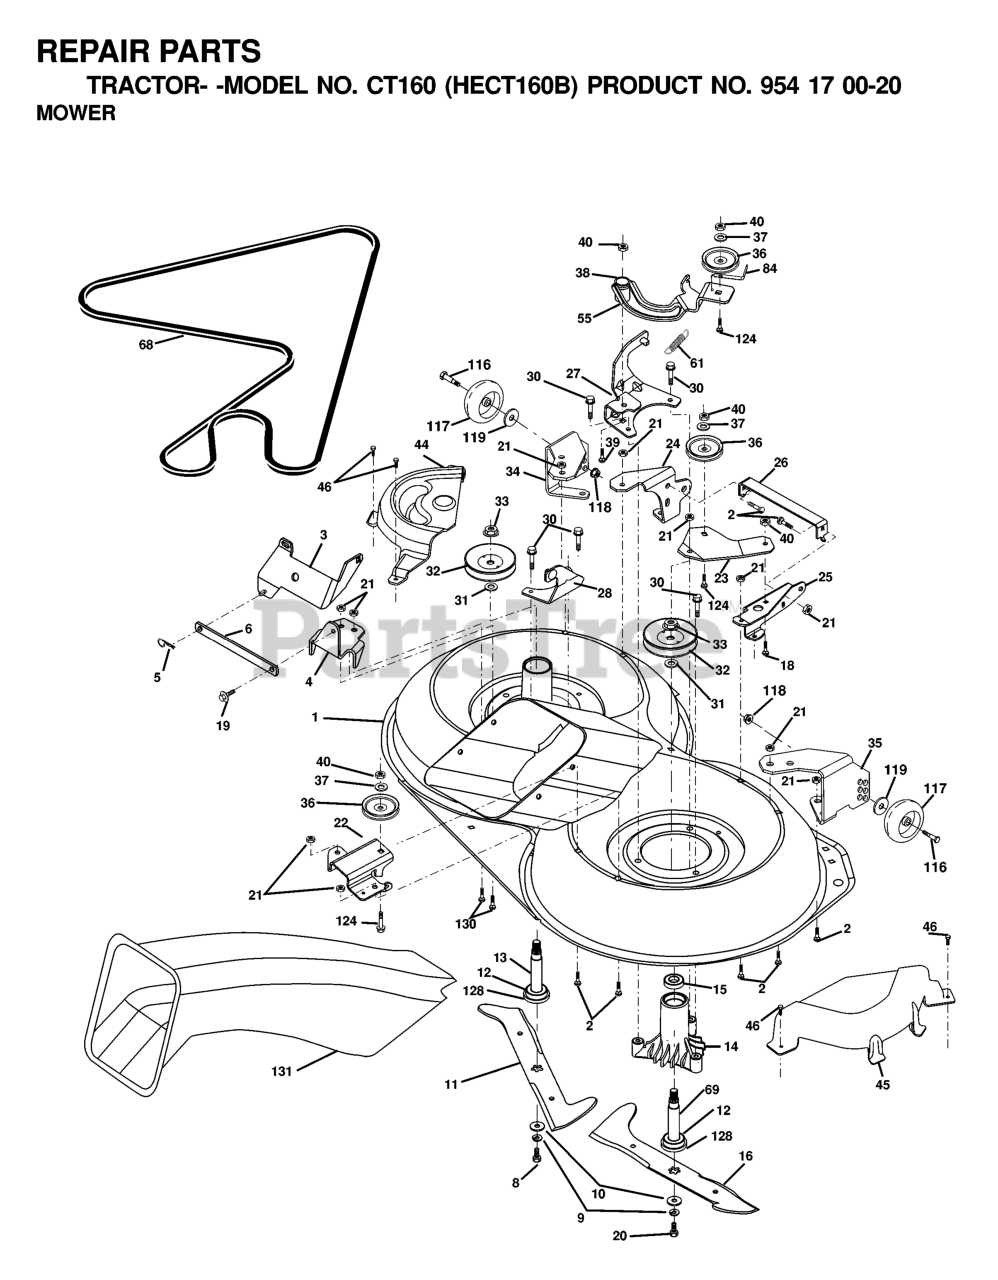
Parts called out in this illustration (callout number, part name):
1	Housing Asm. Mower 107 CRD
2	RP BOLT 5/16-18 X3/4 ZN/YEL GR
5	RETAINER-SPRNG RB
6	BAR.SWAY.92.CRD
8	BLADE BOLT
9	LOCKWASHER
10	WASHER.BLADE
11	BLADE - LH (CTH150)
12	BEARING.BALL.#6204.(MANDREL)
13	SHAFT ASM VENT
14	HOUSING.MANDREL.VENTED (MACHD)
16	BLADE - RH (CTH150)
18	BOLT D
19	BOLT SHD 5/16-18
21	LOCKNUT
22	BRACKET.IDLER.RR.107.CRD
25	BRACKET.SUSPENSION.RF.107.CRD
26	BRACE.SUPT.SUSP.FRT.CRD
28	BRACKET
30	SCREW THDROL ROLLING WASHER HD
31	WASHER
32	PULLEY/MANDREL
33	NUT
34	BRACKET
36	PULLEY.IDLER.4.25
37	WASHER
44	Cover Mandrel Lh 107 CRD
45	MANDREL COVER RH
46	SCREW.1/4-20X5/8
55	ARM.IDLER.107.CRD
61	SPRING.TENSION.BELT
68	HEX-BELT 107 MOWER
69	SHAFT.ASM.W/LWR.BRG.RH.THREAD
84	KEEPER, BELT IDLER
116	BOLT, SHOULDER
117	WHEEL GAGE DONUT
118	LOCKNUT
119	WASHER.5/16.FLAT.STE.STD.
124	BOLT.3/8-16X1.50
128	WASHER FELT
130	BOLT.CARR.SQNK.5/16-18UNC.X3/4
131	CHUTE BAGGER
158	SCREW LT
